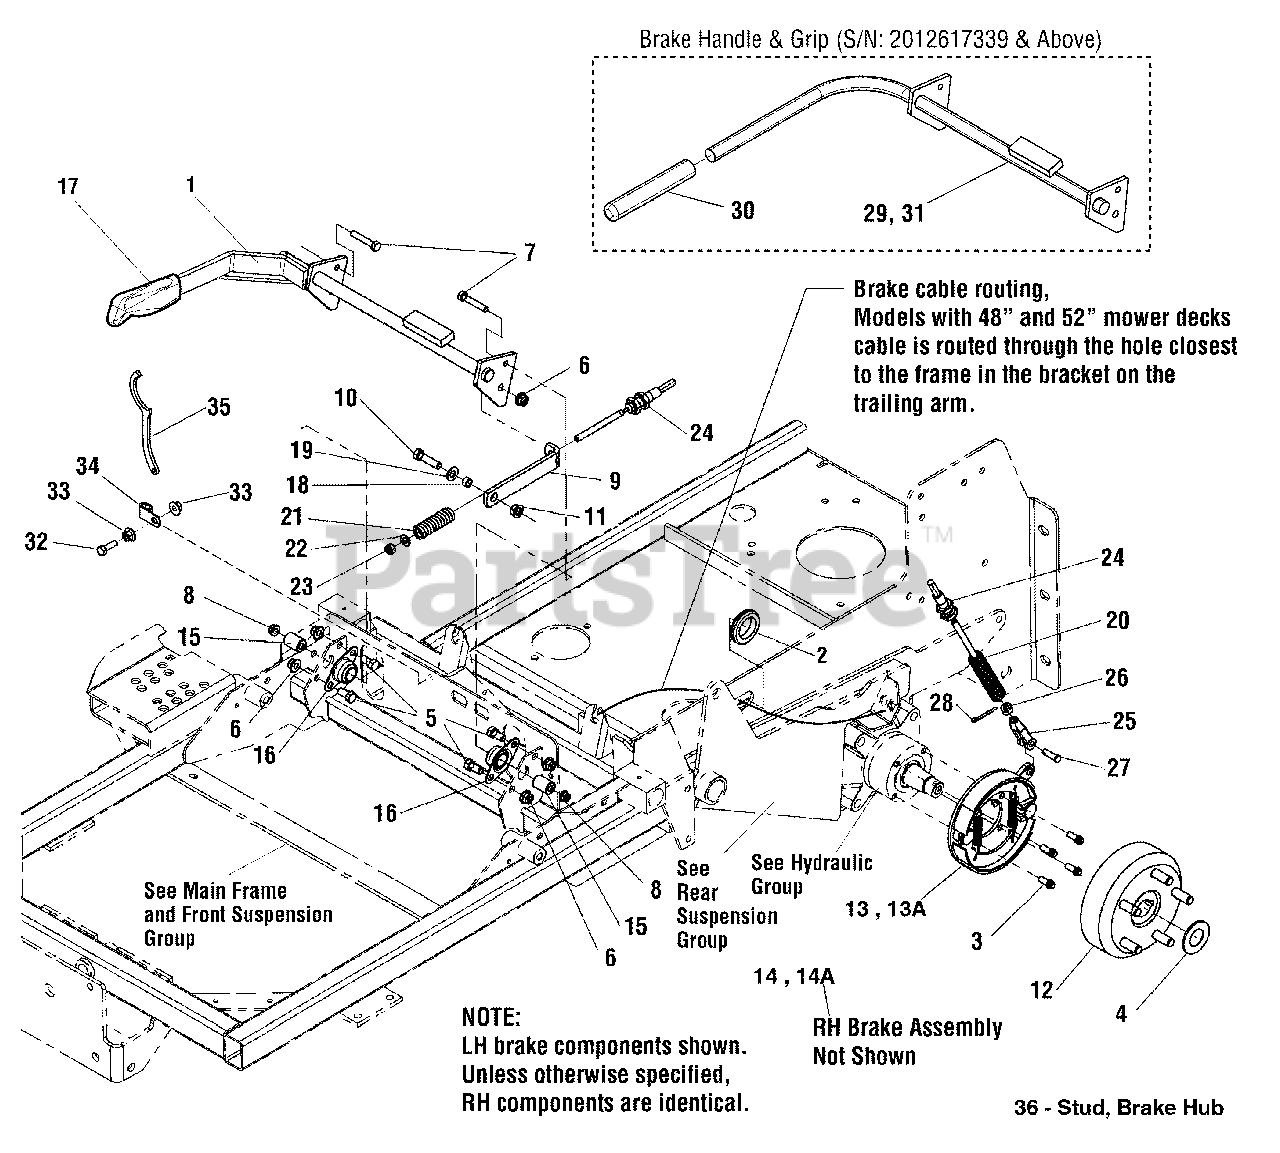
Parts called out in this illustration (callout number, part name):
1	BRAKE SHAFT - ORANGE
2	GROMMET, 1-1/4"
3	BOLT, 5/16-18 X 3/4" 12 Point Flange
4	WASHER, 1 x 2
5	BOLT, 3/8-16 X 3/4"
6	NUT, 3/8-16 Hex Nylock Flange
7	BOLT, 5/16-18 X 1-3/4"
8	NUT, 5/16-18 Hex Nylock Flange
9	LINK, BRAKE LOCK - BLK
10	BOLT, 3/8-16 X 1-1/2"
11	NUT, 3/8-16 Hex Serrated Flange
12	BRAKE DRUM, 6", 5 BOLT, KNOTT
13	BRAKE ASSEMBLY, LH
13A	BRAKE SHOE ASM, LH, KNOTT
15	SPACER, .32 X .75 X 1.06
16	BEARING, FLANGE
17	GRIP
18	SPACER, .38 X .50 X .27
19	WASHER, 3/8" SAE
20	SPRING, Compression
21	SPRING, Compression
22	WASHER, 5/16" SAE
23	NUT, 5/16-24 Hex Nylon Lock
24	PARKING BRAKE CABLE
25	CLEVIS, 5/16-24, Plastic
26	NUT, 5/16-24 Hex
27	CLEVIS PIN, 5/16" X 1"
28	COTTER PIN, 1/8" X 1-1/4"
29	BRAKE SHAFT - ORANGE
30	GRIP
31	WELD, BRAKE SHAFT - BLK
32	BOLT, 5/16-18 X 1 GD5 YZ
33	NUT, 5/16-18 HEX SERRATED FLANGE (LARGE)
34	CLAMP, 5/16, DOUBLE, WIRE & TUBE
35	SPANNER WRENCH
36	STUD, BRAKE HUB (SV)
